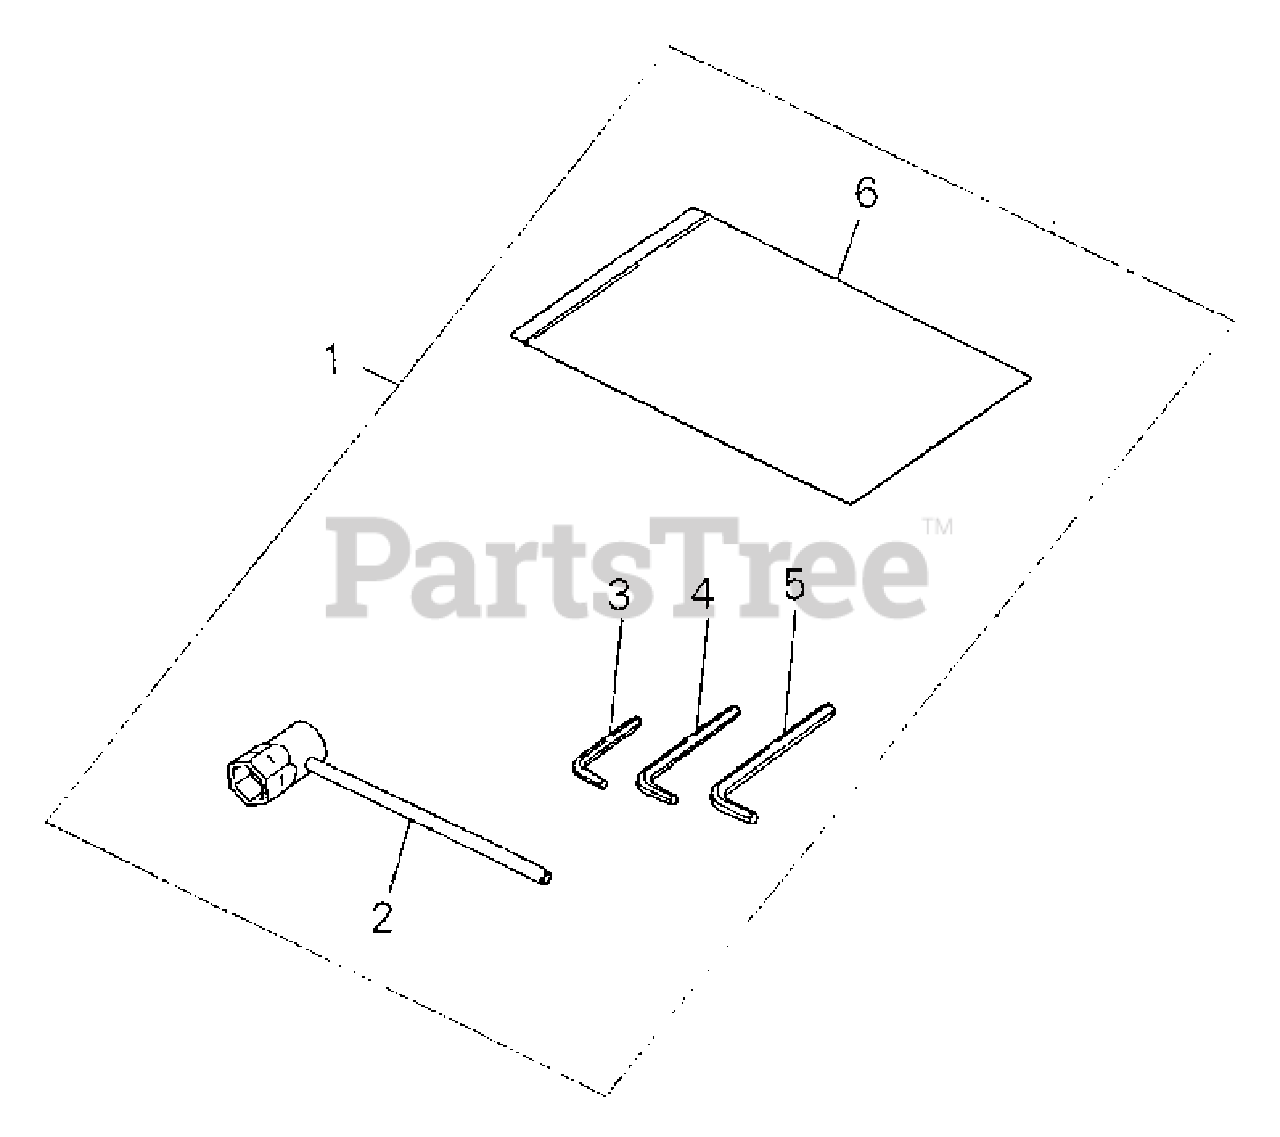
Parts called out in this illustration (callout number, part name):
1	TOOL KIT, SERVICE
2	T-WRENCH 19 MM
3	WRENCH, ALLEN 3 MM
4	WRENCH, ALLEN 4 MM
5	WRENCH, ALLEN 5 MM
6	BAG, TOOL
